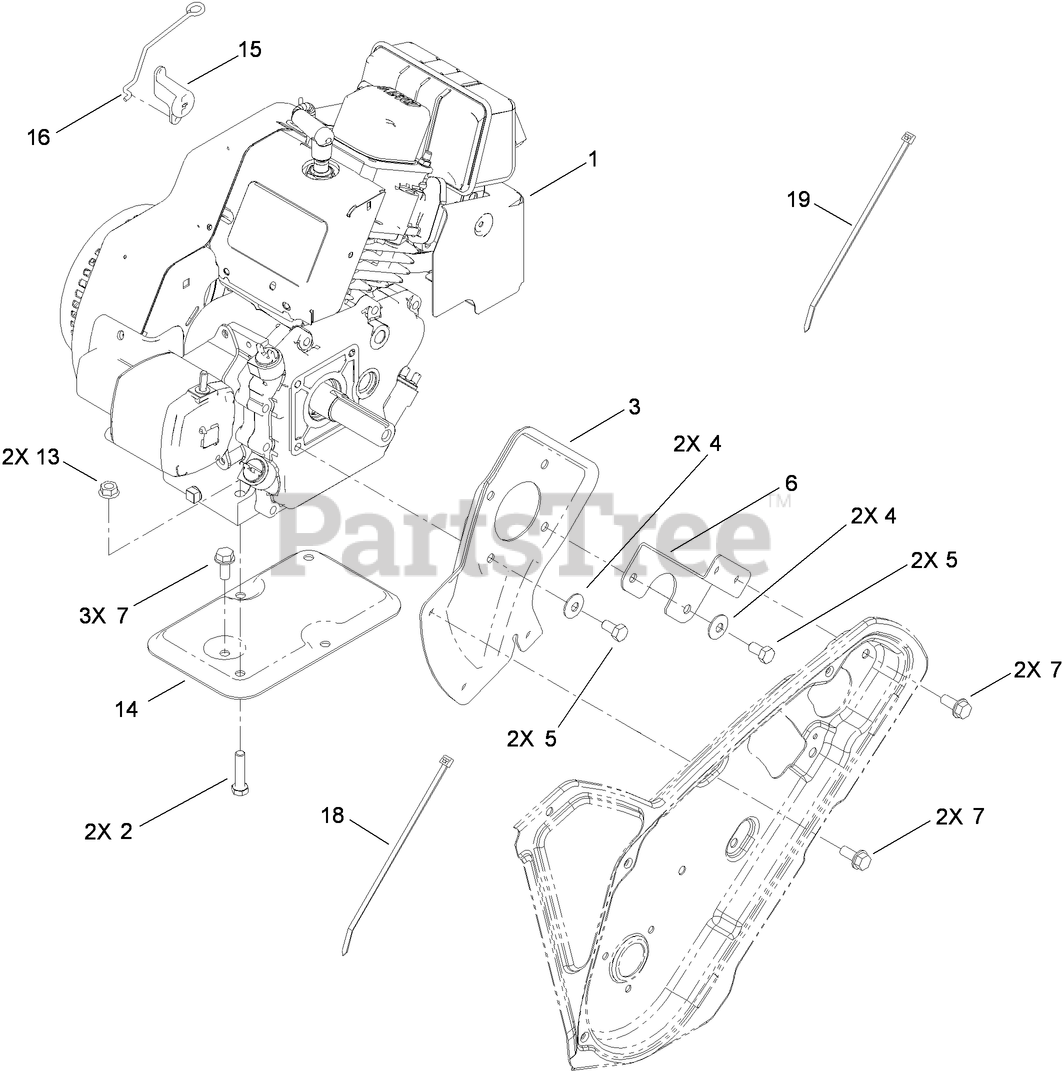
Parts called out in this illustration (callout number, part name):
2	SCREW-HH
3	PLATE-ENGINE, PTO
4	WASHER-BELLEVILLE
5	SCREW-HH
6	SUPPORT-ENGINE, SIDE
7	SCREW-HWHTF
13	NUT-HF
14	SUPPORT-ENGINE
15	BELLCRANK-CHOKE, 4 STROKE
16	LINK-CHOKE KNOB, OHV
18	TIE-CABLE
19	TIE-CABLE
